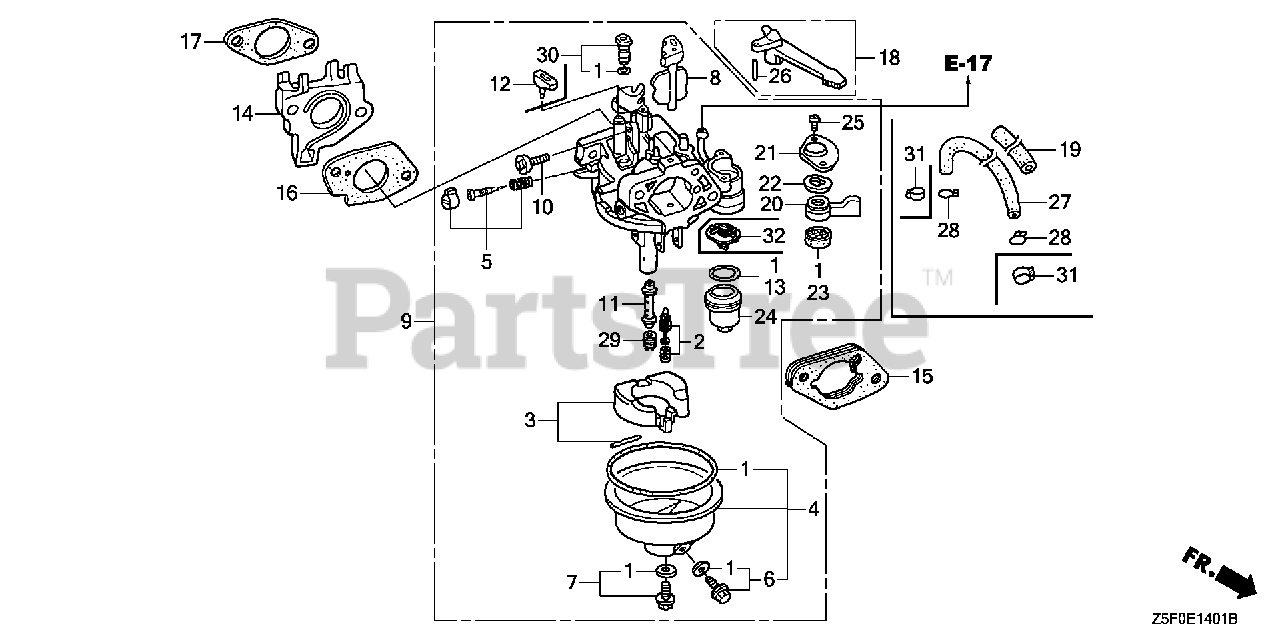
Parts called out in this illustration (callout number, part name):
1	GASKET SET (INCLUDES 16173-001-004)
2	VALVE SET, FLOAT
4	CHAMBER SET, FLOAT
5	SCREW SET, PILOT
6	SCREW SET, DRAIN
9	CARBURETOR ASSY. (BE70R A)
10	SCREW, THROTTLE STOP
11	NOZZLE, MAIN
12	COLLAR, SETTING
13	GASKET, FUEL STRAINER CUP
14	INSULATOR, CARBURETOR
15	SPACER, CARBURETOR
16	GASKET, CARBURETOR
17	GASKET, INSULATOR
18	LEVER, CHOKE (STD)
20	LEVER, PETCOCK
21	PLATE, LEVER SETTING
22	SPRING, PETCOCK LEVER
23	GASKET, PETCOCK
24	CUP, FUEL STRAINER
25	SCREW, PAN (3X6)
26	PIN, SPRING (2X12)
29	JET, MAIN (#80)
29	JET, MAIN (#82)
29	JET, MAIN (#85)
30	JET SET, PILOT (#38)
32	FILTER, CUP
